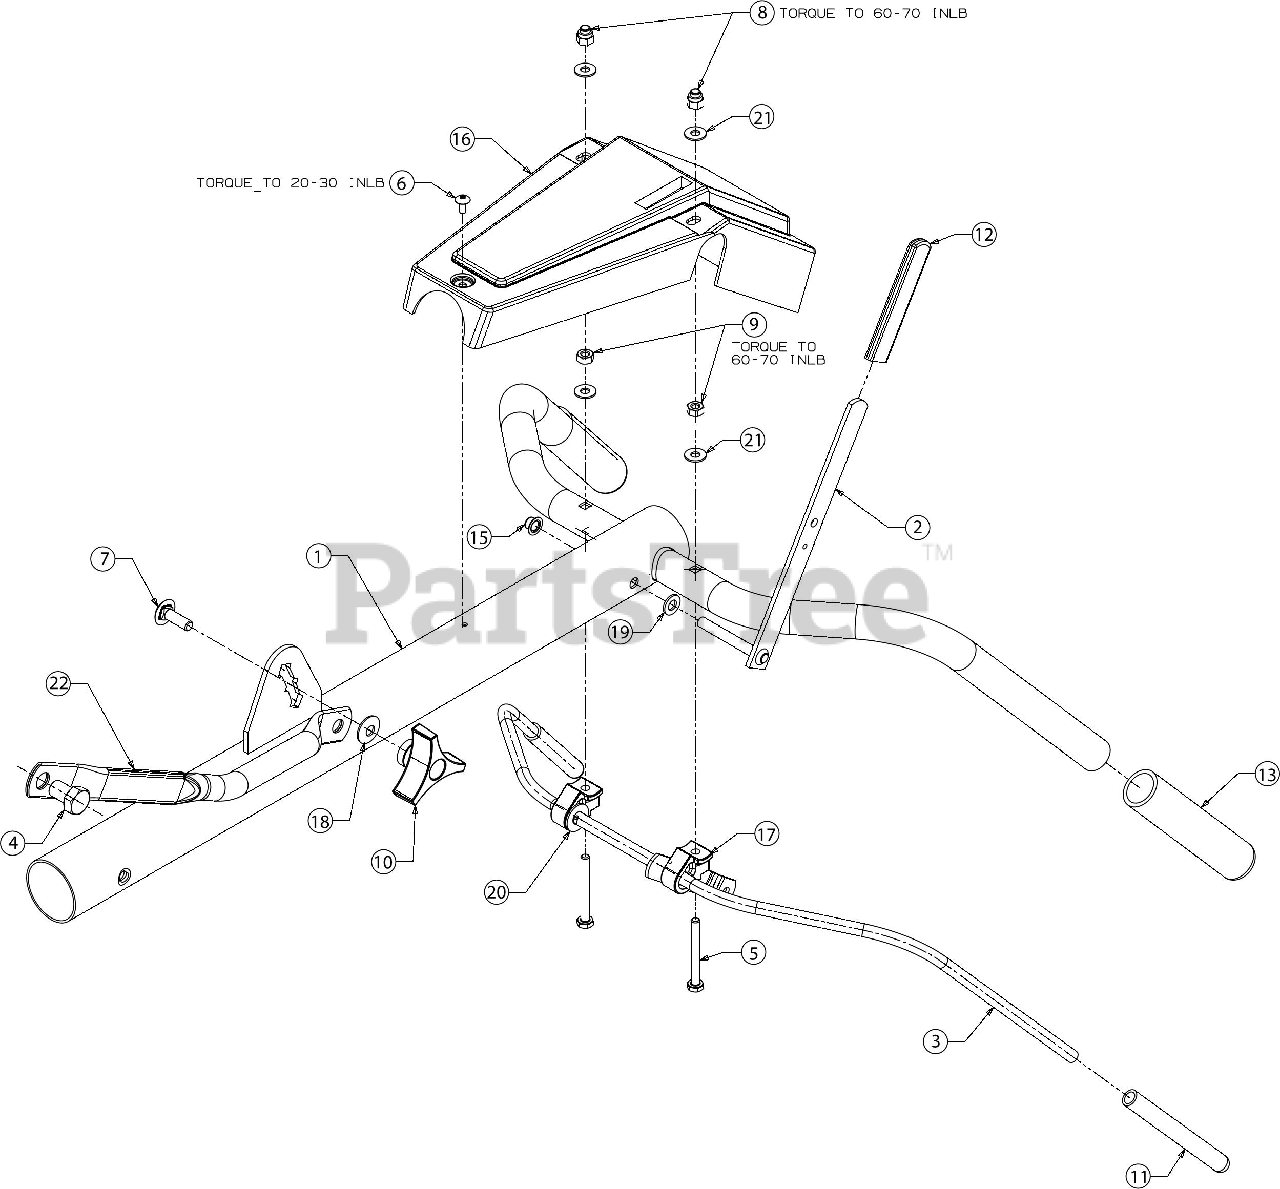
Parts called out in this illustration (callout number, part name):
2	REVERSE HANDLE ASSEMBLY
3	CLUTCH HANDLE ASSEMBLY
4	BOLT 1/2-20 X .75 GR5
5	SCREW 1/4-20 X 2.25 GR5
6	SCREW #10-16 X .500
7	SCREW 5/16-18 X 1.00
8	HEX ACORN NUT
10	HANDLE KNOB
11	CLUTCH GRIP
12	REVERSE LEVER GRIP
15	SPEED NUT
16	HANDLE COVER PANE
17	HANDLE CLUTCH HOLDER
18	BELL WASHER .337 X.867 X .057
19	FLAT WASHER
20	FLAT WASHER
21	FLAT WASHER .271:.630:.065
